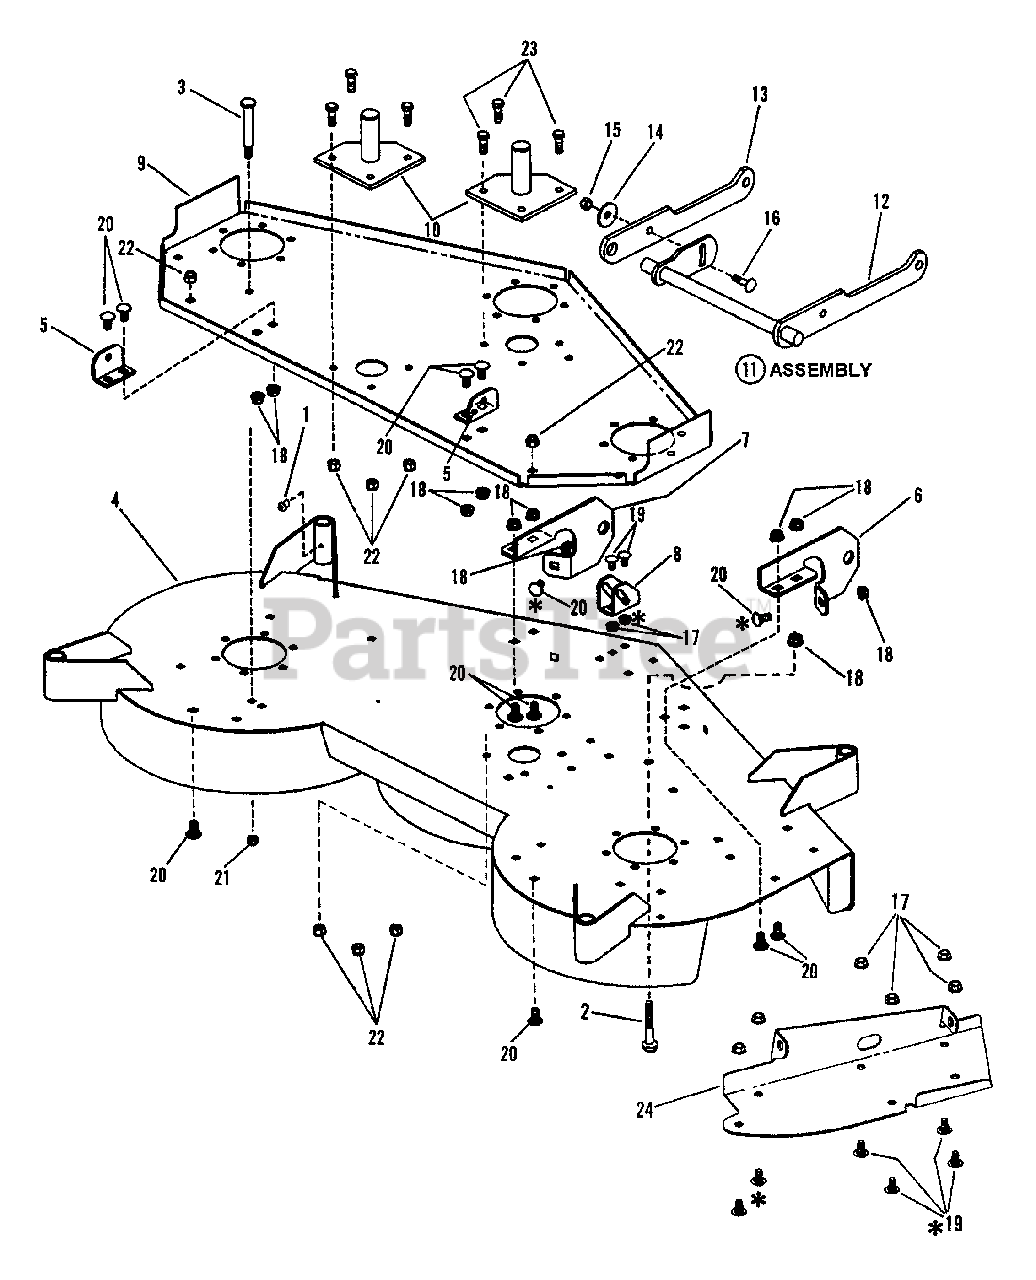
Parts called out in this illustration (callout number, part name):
1	LUBE FITTING, Straight (press-fit for .187 dia. Hole)
2	SCREW, 3/8-16 x 1-1/4" Hex Head Cap, Grade 5
3	BOLT, Gage Wheel
4	WELDMENT, Deck
5	BRACKET, Rear Lift - 48" Deck
6	BRACKET, Front Hanger - Right Hand
7	BRACKET, Front Hanger - Left Hand
8	BRACKET, Front Hanger - 48" Deck
9	STIFFENER, 48" Deck
10	WELDMENT, Idler Pivot
11	ASSEMBLY, Front Lift Arm - 97 Model Year
12	WELDMENT, Front Lift Arm
13	ARM, Lift
14	WASHER, Cone 3/8" I.D.
15	NUT, 3/8-16 Hex
16	BOLT, 3/8-16 x 1-1/4 Grade 5
17	NUT, 5/16-18 Hex Flange Lock, Grade 5
18	NUT, 3/8-16 Hex Flange Lock
19	BOLT, 5/16-18 x 5/8" Short Neck Carriage, Grade 5
20	BOLT, 3/8-16 x 3/4" Short Neck Carriage, Grade 2
21	NUT, 5/16-1 8 Hex Nylo c
22	NUT, 3/8-16 Hex Nyloc
23	SCREW, 3/8-16 x 1" Hex Head Cap, Grade 5
24	BRACKET, Hinge
